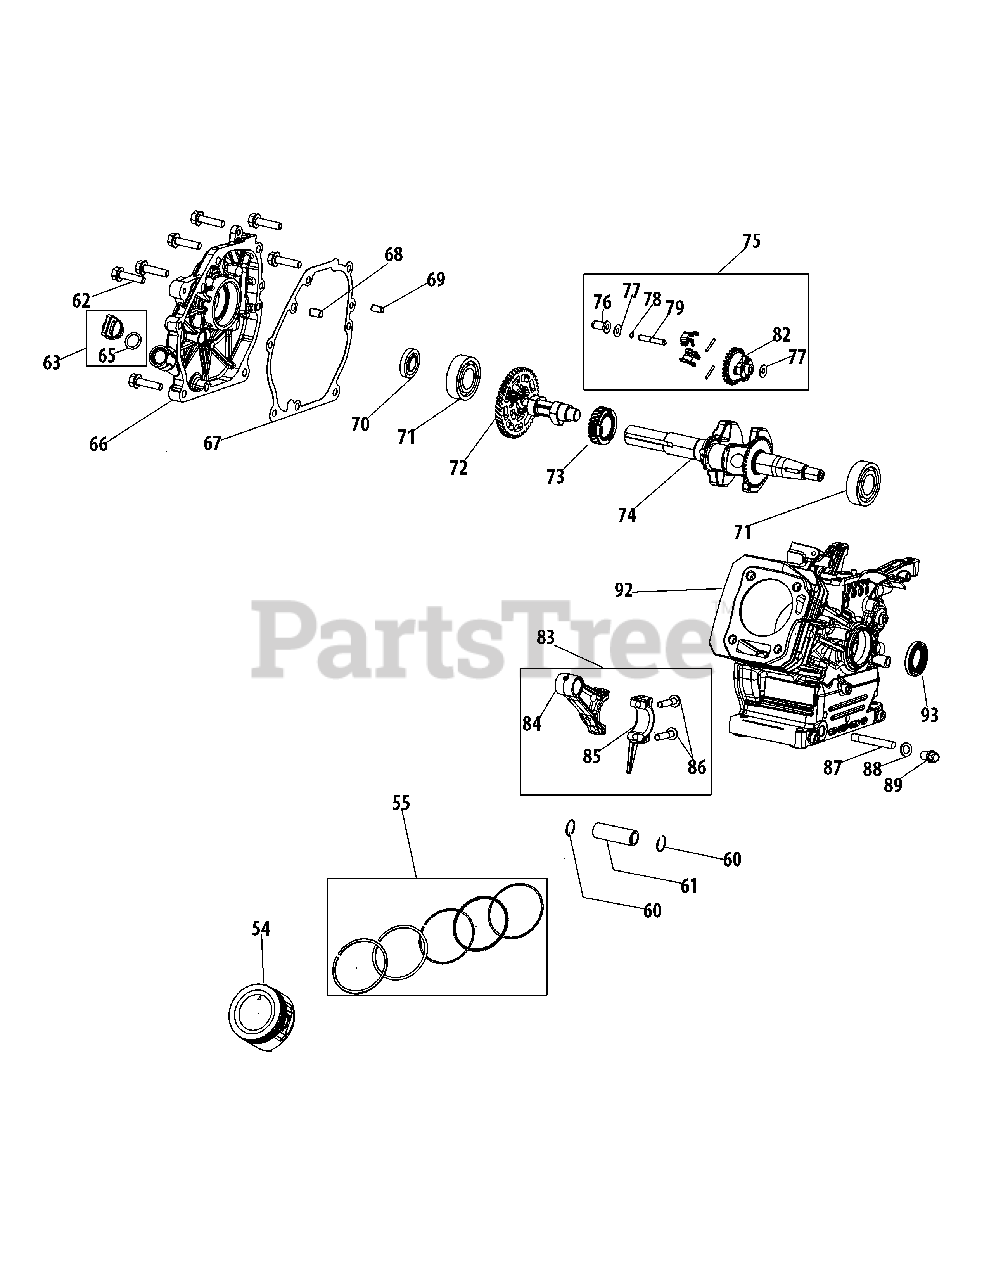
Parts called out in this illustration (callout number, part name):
54	Piston
55	Piston Ring Set
60	Circlip
61	Piston Pin
62	Bolt, M6×32
63	Oil Plug
65	O-Ring, 15.8×2.5
66	Crankcase Cover
67	Gasket, Crankcase
68	Pin, 9×14
69	Pin, 7×14
70	Oil Seal, 25×41.25×6
71	Bearing, 6205
72	Camshaft
73	Drive Timing Gear
74	Crankshaft
75	Governor Gear
76	Governor Cup
77	Washer, 6.2×0.6×15
78	Retaining Ring
79	Governor Shaft
82	Governor Gear
83	Connecting Rod Assembly
84	Connecting Rod
85	Connecting Rod Cap
86	Connecting Rod Bolt
87	Oil Drain Pipe
88	Washer, 10×1.5×16
89	Earth Bolt
92	Crankcase
93	Oil Seal, 25×41.25×6
